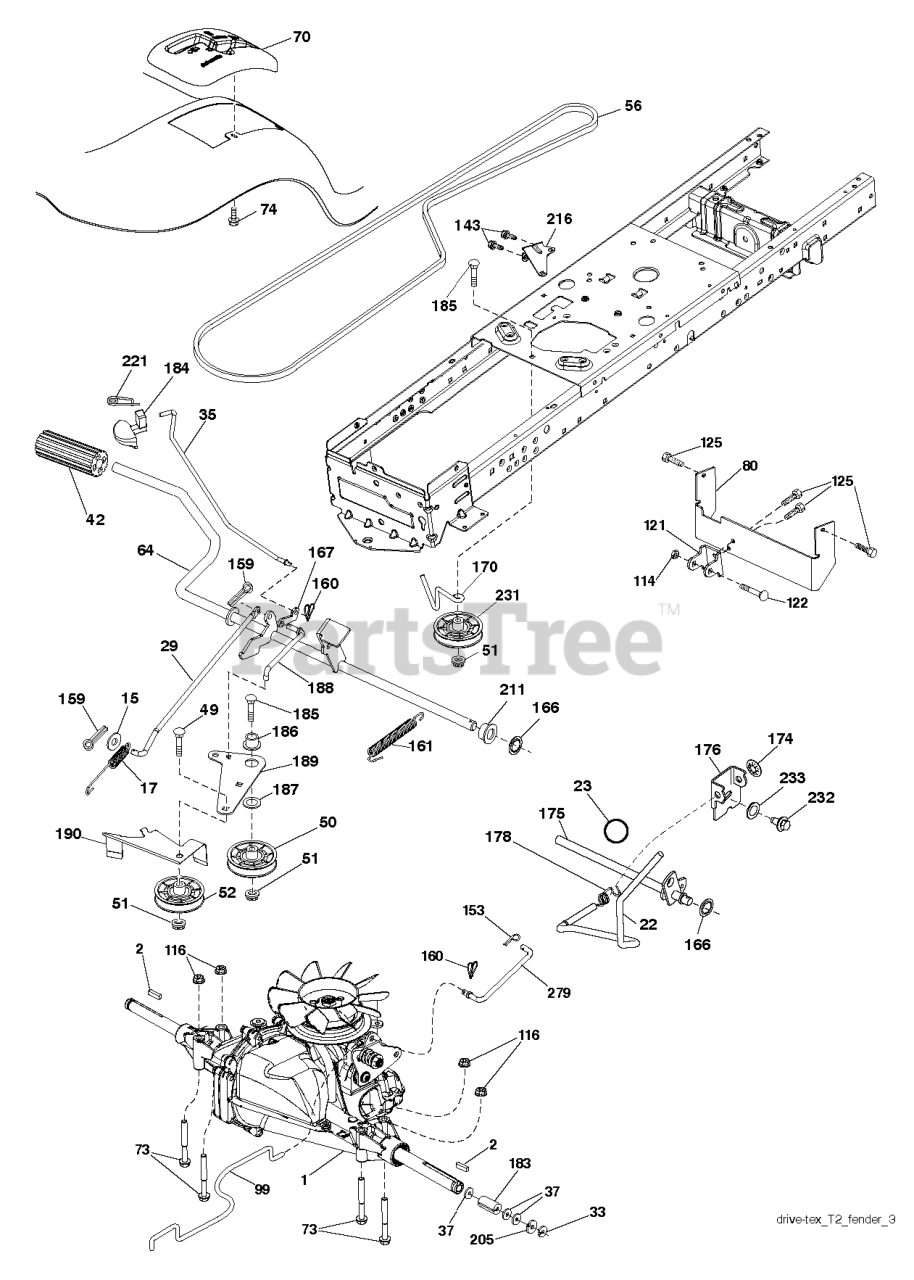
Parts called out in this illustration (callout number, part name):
2	SQUARE KEY
15	WASHER
17	SPRING.BRAKE.HG3000/3500
22	ROD.SHIFT.FENDER.TLT.2006
23	KNOB.DELUXE.(PISTOL.GRIP).BLAC
29	ROD.BRAKE.T2.TEX
35	ROD.CNTRL.PARK.PREDATOR.LT.TEX
42	PEDAL COVER T
50	IDLER.FLAT.910.OFFSET
51	NUT LOCK FLG 3/8-16 UNC
52	IDLER.V-GROOVE.910.OFFSET
56	BELT.GROUND.DRIVE.T2-HP.CE
64	SHAFT.ASM.PEDAL.BRAKE.
70	CONSOLE.SHIFT.STL.HYD.TEX.GREY
73	BOLT HEX 5/16-18 GR 5
74	SCREW.HI-LO.CONSOLE
80	STRAP.TORQUE.T2
99	ROD.ASM.BYPASS.SPRING.T2.FS
114	NUT.71038.31-18.HEX.NYLOCK
116	NUT LOCK HEX FLANGE 5/16-18
121	BRACKET STRAP TORQUE
122	BOLT.5/16-18X2.5
125	SCREW
143	Screw 5/16-18 x 1/2 Hex, Self Tapping 5/16-18 x 1/2
153	RETAINER M
159	COTTER PIN
160	RETAINER CLIP
161	SPRING, RETURN LT
166	NUT.PUSH.625
167	LATCH.BRAKE.SPRING
170	KEEPER.CENTER SPAN.1.688
174	NUT.PUSH.500.2006
175	SHAFT.ASM.SHFT.T2.TLT
176	ARM.CLEVIS.ROD.SHIFT
178	SPRING.SHIFT.GT2006
183	SPACER, AXLE PVST
184	HANDLE.PARKING.BRK.PRED.LT.RED
186	SPACER.RETAINER
187	WASHER 12/32X2X10GA
188	RP.LINK.CLUTCH.GROUND.DRIVE
189	BELLCRANK.GROUND.DRIVE.TEX.
190	KEEPER.BELLCRANK.DRIVE
211	BUSHING.SHAFT.BRAKE.HAND
216	BRACKET.PULLEY.IDLER.W/TEX
221	RETAINER.SPRING.CLIP.H
231	IDLER.V-GROOVE.1.688.OFFSET
232	BOLT FIN HEX 7/16-14 X 1
233	WASHER SERRATED
279	LINK.SHIFT.T2
